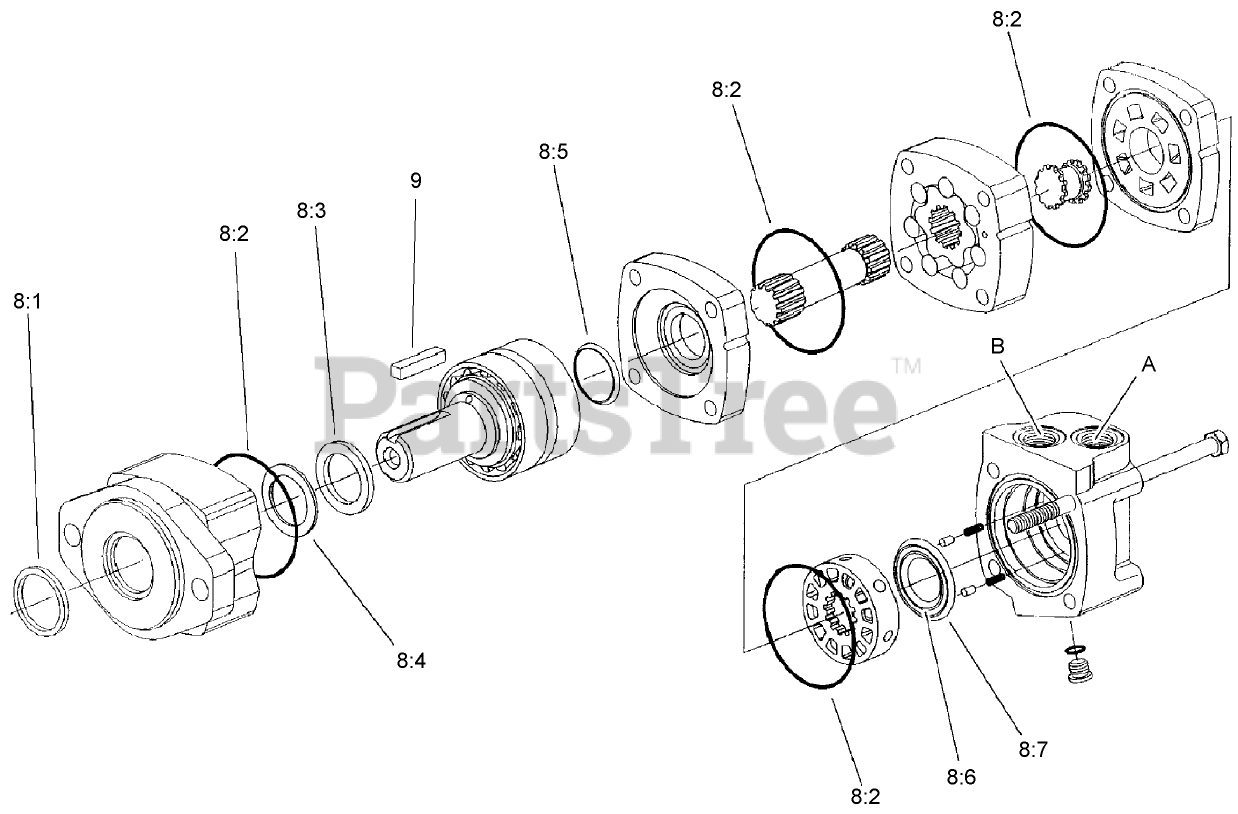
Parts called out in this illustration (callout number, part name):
8	SEAL KIT
8:1	Seal-Dust (Not serviced separately)
8:2	Seal-Exclusion, Shaft (Not serviced separately)
8:3	Seal-Shaft (Not serviced separately)
8:4	Ring-Back-Up (Not serviced separately)
8:5	Seal-Face, Shaft (Not serviced separately)
8:6	Seal-Face, Inner (Not serviced separately)
8:7	Seal-Face, Outer (Not serviced separately)
9	KEY-SQUARE
